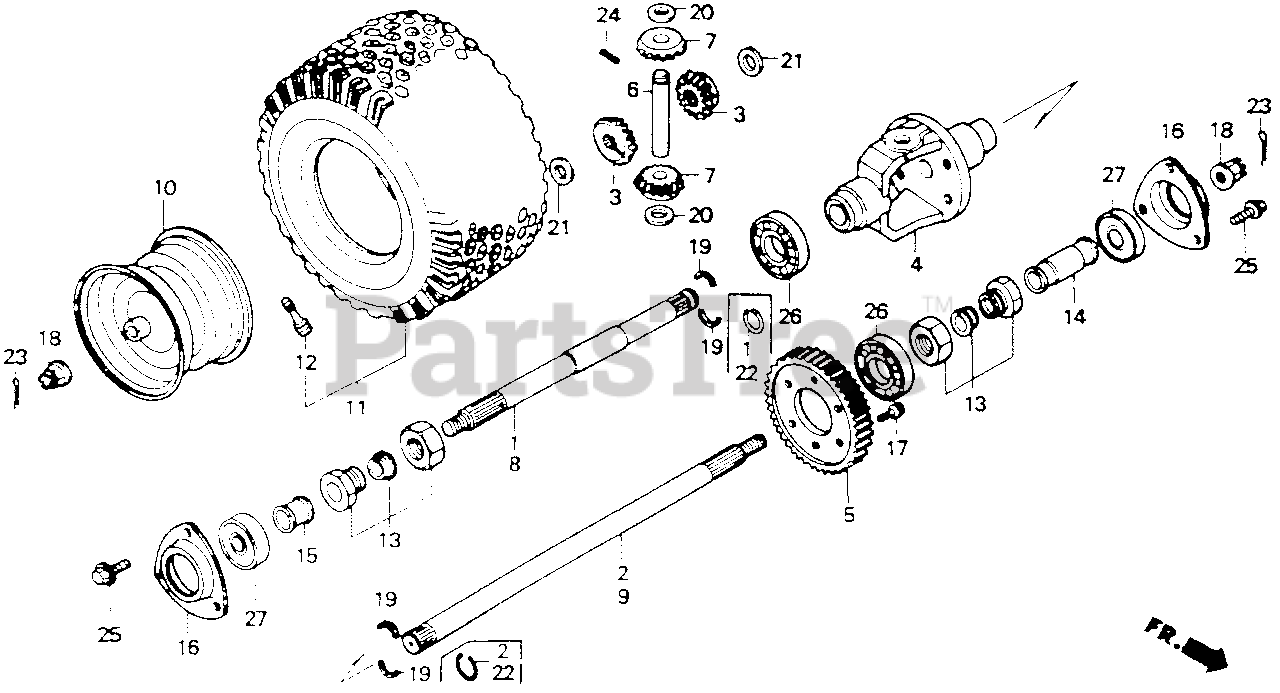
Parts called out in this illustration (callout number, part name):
3	GEAR, DIFFERENTIAL
4	CASE, DIFFERENTIAL GEAR
5	GEAR, FINAL DRIVEN (48T)
6	SHAFT, DIFFERENTIAL
7	PINION, DIFFERENTIAL
8	SHAFT, R. AXLE
9	SHAFT, L. AXLE
10	WHEEL, RR.
10	WHEEL, RR. *NH35M* (CLOUD SILVER METALLIC) (NOT AVAILABLE)
11	TIRE ASSY., RR. (OHTSU)
12	VALVE, RIM
16	HOLDER, BEARING
17	BOLT, SPECIAL (10X20)
18	NUT, AXLE (14MM)
19	COTTER (15MM)
20	WASHER A, DIFFERENTIAL PINION
20	WASHER B, DIFFERENTIAL PINION
20	WASHER C, DIFFERENTIAL PINION
20	WASHER D, DIFFERENTIAL PINION
21	WASHER, DIFFERENTIAL GEAR
23	PIN, SPLIT (3.0X45)
24	PIN, SPRING (4X32)
25	BOLT, FLANGE (8X14)
26	BEARING, RADIAL BALL (6006)
27	BEARING, RADIAL BALL (6204UU)
